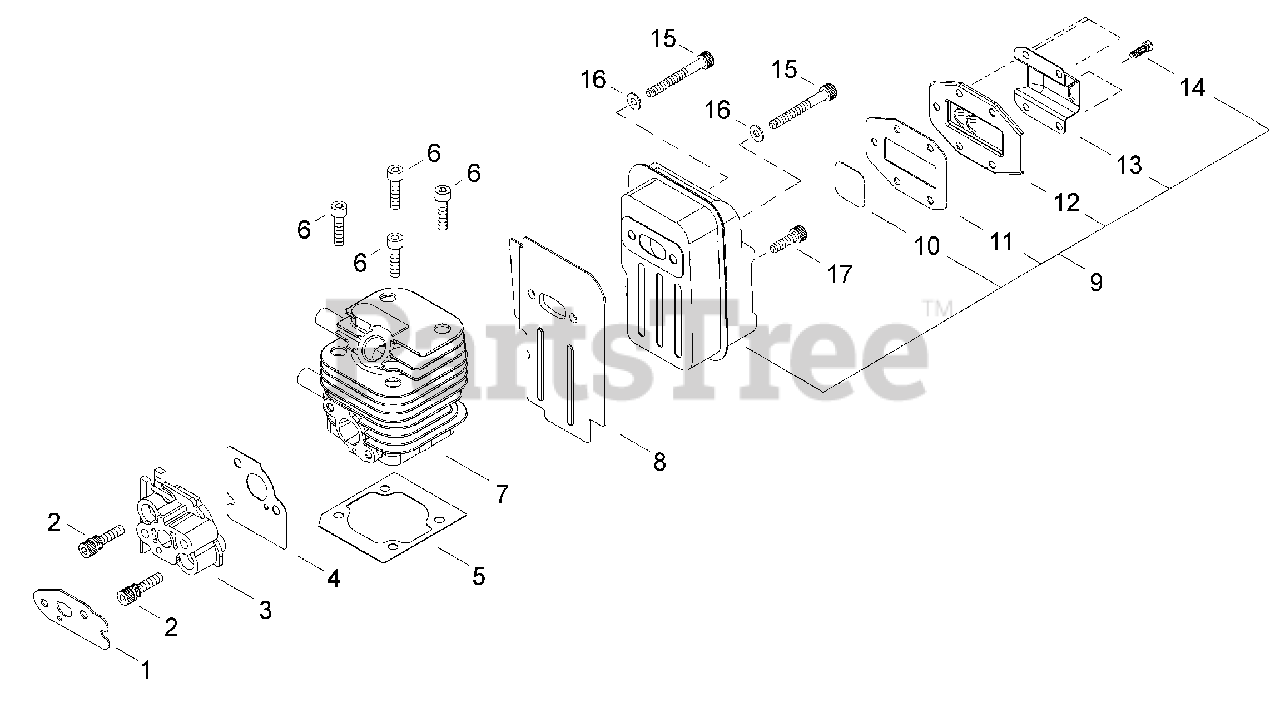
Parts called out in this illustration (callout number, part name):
1-1	GASKET, CARBURETOR
2	BOLT M5×30
3	INSULATOR
4	HEAT SHIELD, INTAKE
5	GASKET, CYLINDER
6	BOLT 5×16
7	CYLINDER
8	HEAT SHIELD, EXHAUST
9	MUFFLER ASSY
10	SCREEN, SPARK ARRESTER
11	GASKET, EXHAUST
12	COVER, SPARK ARRESTER
13	OUTLET, EXHAUST
14	SCREW M4×8
15	BOLT M5×55
16	WASHER SS 5 MM
17	BOLT 5×12
